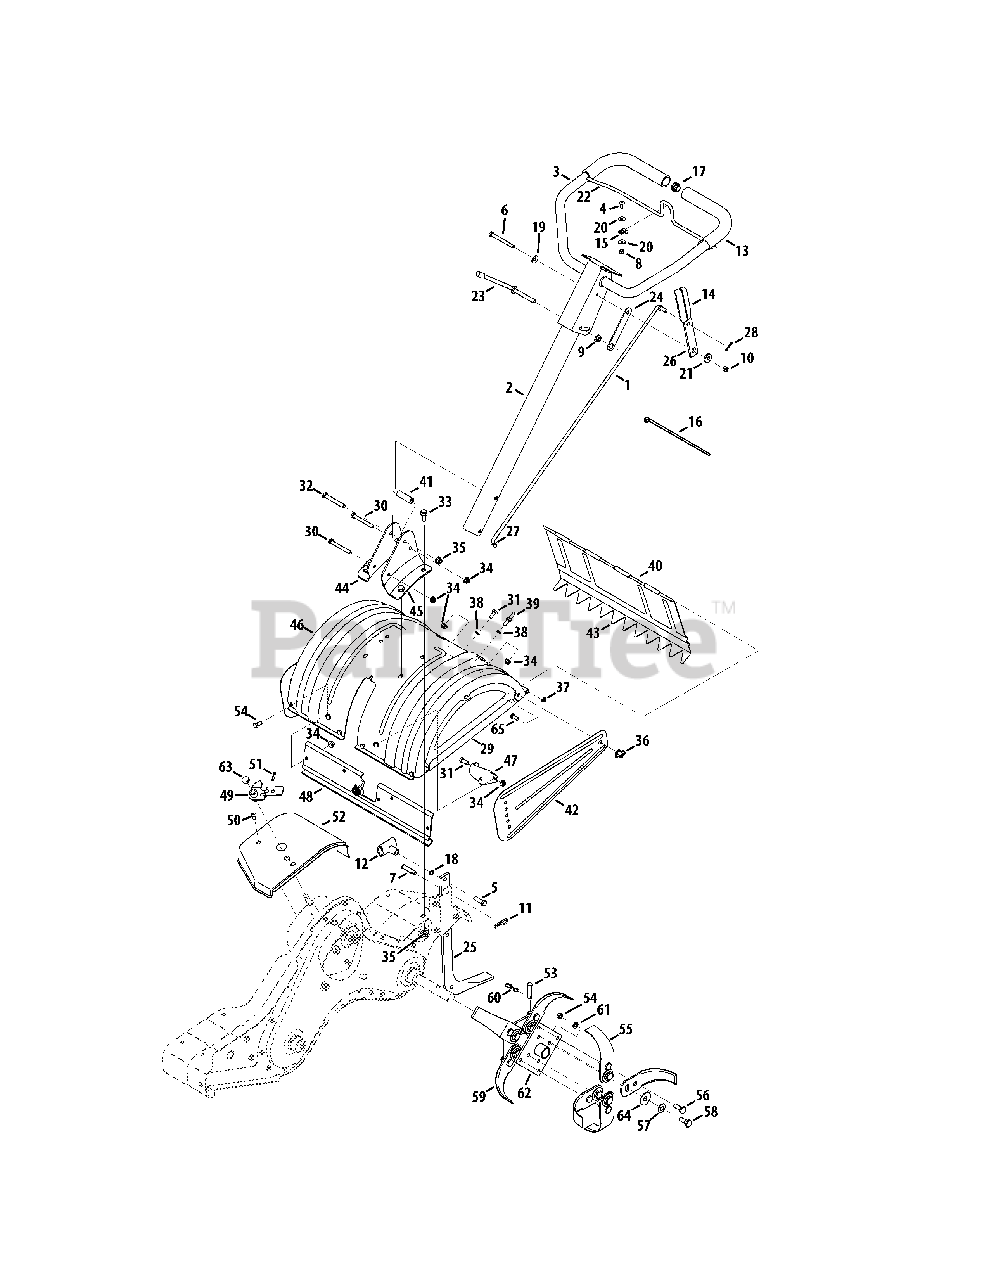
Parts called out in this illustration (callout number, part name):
1	Shaft Rod
2	Lower Handle Tube Assembly
3	Upper Handle Assembly
4	Screw, 1/4-20 x 0.625
5	Hex Head Screw, 3/8-16:1.25
6	Hex Head Screw, 5/16-18 x 3.25
7	Clevis Pin, .375 X 1.75
8	Hexlock Nut, 1/4-20
9	Flangelock Nut, 3/8-24
10	Hexlock Nut, 5/16-18
11	Cotter Pin, .125 X 1.75 INTERNAL
12	Small Tee Knob
13	Foam Grip, .970 x 11.0
14	Grip, .1875 x 1.00
15	Battery Clamp, 5/16
16	Cable Tie, 8.5 LG
18	Washer, Flat, .385 x .620 x .033
19	Washer, Bell, .340 x .872 x .060
20	Washer, Flat, .260 x .720 x .060
21	Spacer, Shoulder, .50 x .190 x .360
23	Handle Adjustment Crank
24	Hex Nut Retainer Bracket
25	Tiller Depth Control
26	Shaft Rod Lever
27	Washer, Rubber, .33 ID x .125
28	Cotter Pin, .072 x 1.12 LG
29	End Cover Assembly
30	Hex Head Screw, 5/16-18 x 2.75
31	Hex Head Screw, 5/16-18 x .75
32	Hex Head Screw, 3/8-16 x 2.75
33	Hex Head Flange, 3/8-16 x .875
34	Flangelock Nut, 5/16-18
35	Flangelock Nut, 3/8-16
36	Wing Nut, 5/16-18 W/ Bell Washer
37	Speed Nut Cap, 1/4 ROD
38	Washer, Flat, .344 x .62 x .033
39	Screw, Hex, 5/16-18 x .75
40	Tiller Flap Rod
41	Spacer, .322 x .625 x 2.00
43	Rear Tine Shield
44	RH Handle Mount Bracket
45	LH Handle Mount Bracket
47	FRT Tine Shield Bracket
48	FRT Tine Shield Spacer Bracket
49	Shift Crank Assembly
50	Screw, 1/4-14 x .625
51	Spiral Pin, 3/16 x 1.0
53	Clevis Pin
54	Hex Nut, 3/8-24
55	13" Articulating Tine
56	Shoulder Bolt
57	Bell Washer, .515" ID x 1.14" OD
58	Shoulder Bolt
59	Tine Adapter Assembly, 18"
60	Internal Cotter Pin
61	Lock Washer
62	Tine Adapter Plate
64	Washer, Flat, .51 x 1.5 x .07
65	Stud, 5/16-18 x .75
